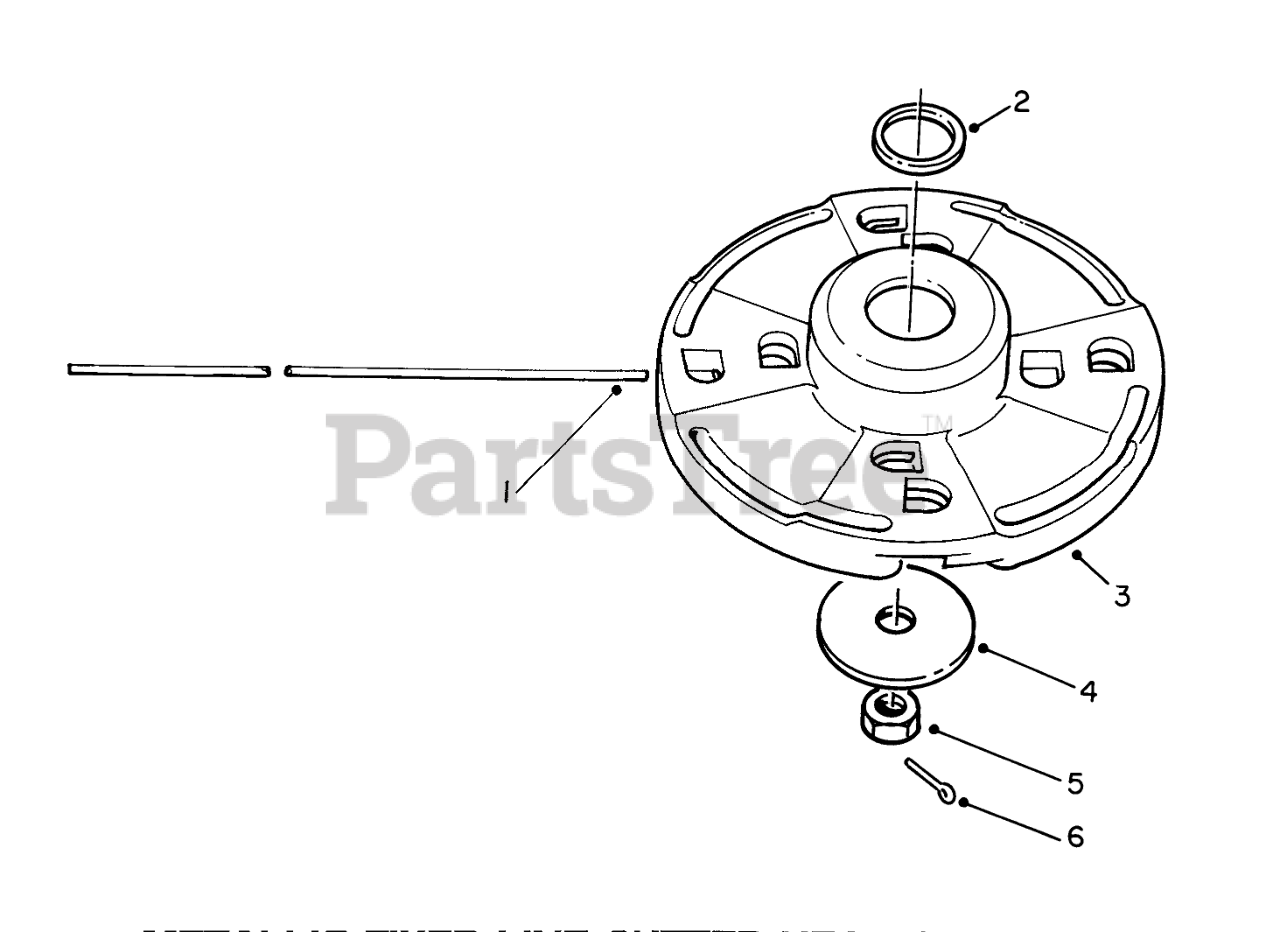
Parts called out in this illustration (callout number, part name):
1	Line-Cutting .105 Dia.
2	SPACER
3	Head Assembly (Incl. Ref. #2)
4	WASHER
6	1/16 X 1 LG COTTER PIN
